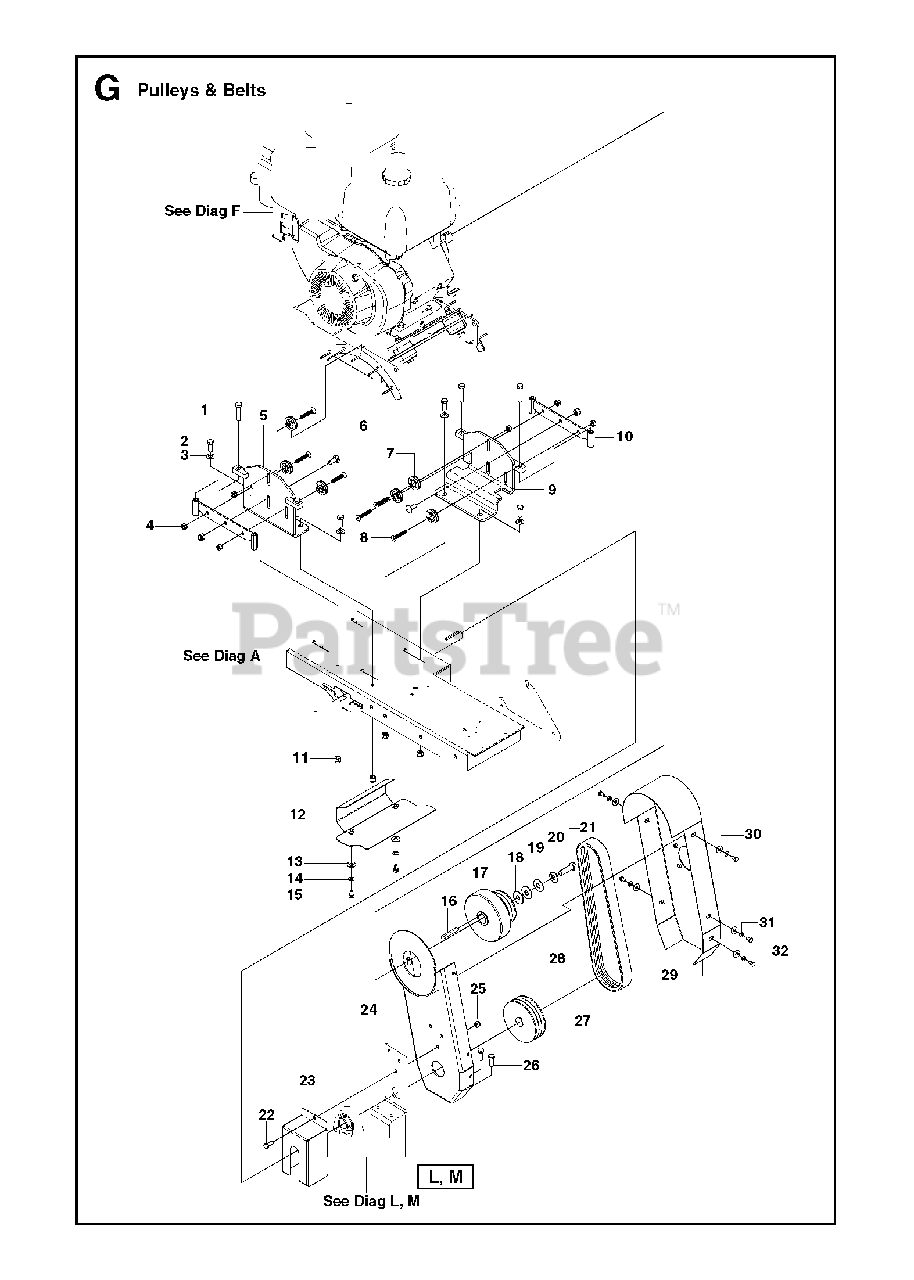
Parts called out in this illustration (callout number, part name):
3	WASHER
11	NUT
14	WASHER
15	SCREW
20	WASHER
22	SCREW
25	NUT
32	HCS ¼-20 X ½ GR 5 ZD
